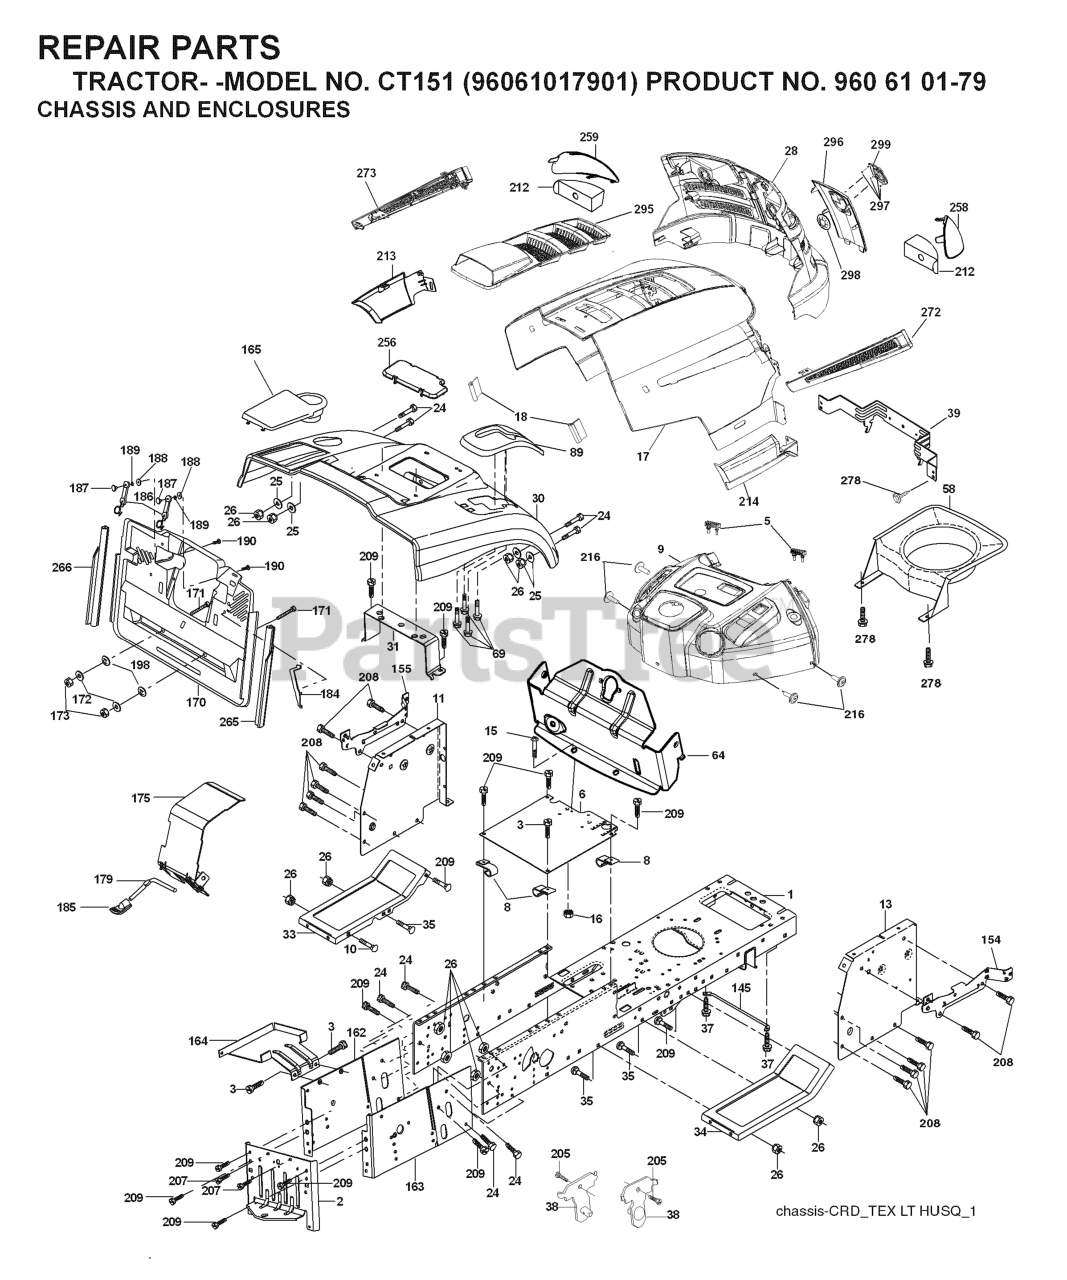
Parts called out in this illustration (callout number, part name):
2	DRAWBAR
3	SCREW 3/8-16X3/4
5	BUMPER DASH
6	PLATE
8	CLIP,INSULATOR
10	BOLT D
11	PANEL.DASH.LH.LTX
13	PANEL ASM, DASH RH
15	Screw, Machine, Truss Head 5/16-18 UNC x 3/4
16	NUT
17	HOOD
18	BUMPER.HOOD.TEX.HUSQVARNA
24	BOLT
25	WASHER
26	NUT
28	RP GRILLE/LENS ASM.
30	CONSOLE.CRD.AUTO.GRY
31	BRACKET SUPPORT FENDER
33	FOOTREST PNT LH
34	FOOTREST PNT RH
35	BOLT
37	Screw 5/16-18 x 1/2 Hex, Self Tapping 5/16-18 x 1/2
38	BRACKET ASM PIVOT MOWER REAR
39	BRACKET PIVOT
69	SCREW.HI-LO.CONSOLE
145	ROD.PIVOT.HOOD
162	BRACKET
163	BRACKET EXTEN CHASSIS RH CRD
165	RP.COVER.BATTERY.CRD.GREY
171	BOLT
172	WASHER
175	DOOR TRAP
179	ROD PIVOT FBI
184	BRACKET.ACTUATOR.BAGGER.SRD
186	LATCH ASSY
187	WELDNUT
189	LOCKWASHER #10
190	SCREW
205	SCREW LT
207	SCREW, 5/16-18 X 1/2
208	SCREW 3/8-16X1/2
209	SCREW, 3/8-16X3/4
212	INSERT REFLECTIVE
213	SKIRT SIDE LH
214	SKIRT SIDE RH
216	SCREW HEXWSHR 1/4-20X3/4
256	COVER FENDER CRD
258	LENS.HUSQVARNA LT.RH
259	LENS.HUSQVARNA LT.LH
265	SEALING
266	SEALING
272	VENT SIDE HOOD RH
273	VENT SIDE HOOD LH
278	SCREW
295	VENT TOP HOOD
296	TRIM
297	CLIP.RETAINER.TINNER.
298	NUT PUSH M
299	RP LOGO
